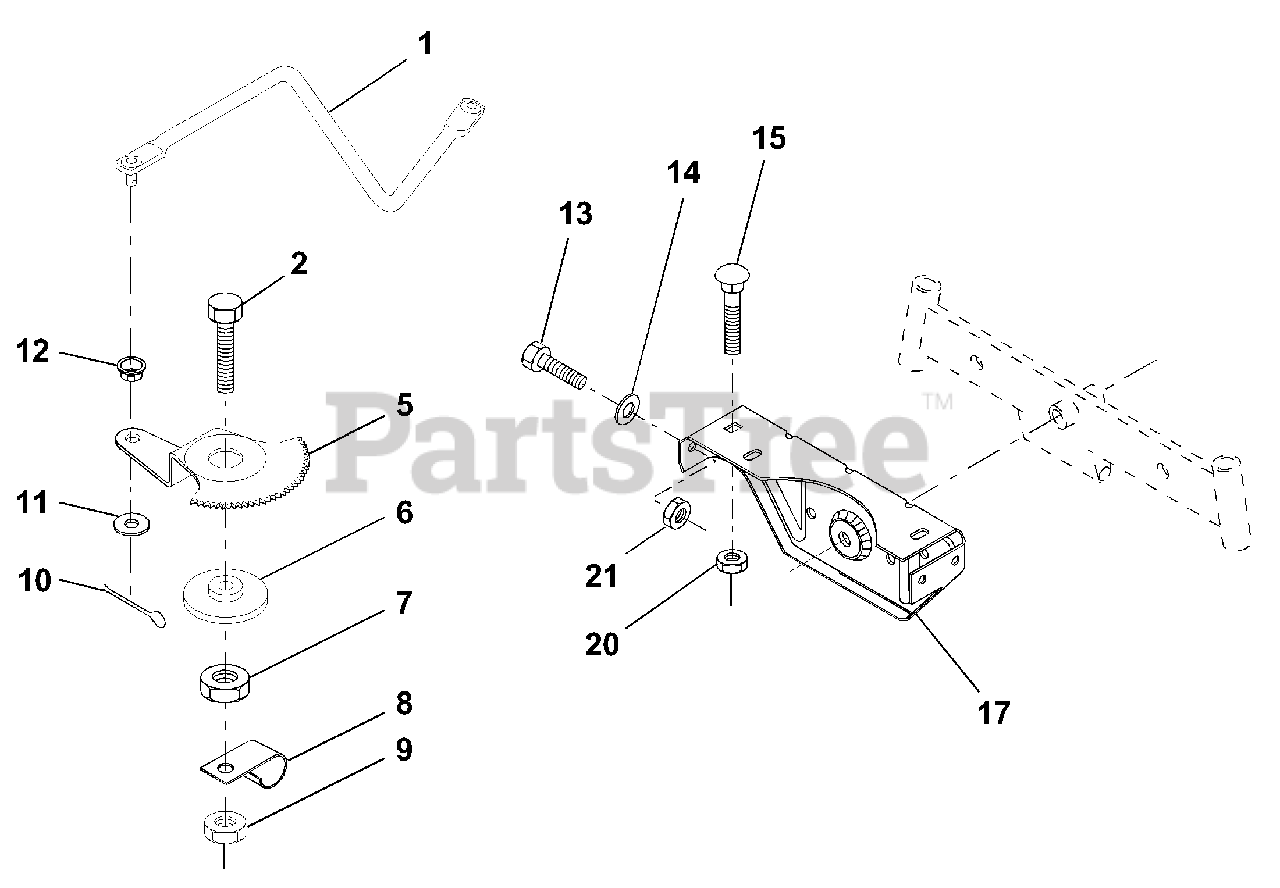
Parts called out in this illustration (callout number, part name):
1	Link, Drag
2	Bolt, Hex, Fin. 1/2-13 x 1-3/4
5	Gear, Sector
7	Nut, Heavy Hex, Top Lock 1/2-13 UNC
8	Clip, Insulated
9	Nut, Crownlock 3/8-16
10	Pin, Cotter 1/8 x 3/4
11	Washer 13/32 x 13/16 x 16 Gauge
13	Bolt, Hex Head 5/16-18 UNC x 1
14	Washer 11/32 x 7/8 x 16 Gauge
15	Bolt, Carriage 3/8-16 UNC x 3/4
17	Support, Front Axle
20	Nut, Hex, Lock Hex w/wsh 3/8-16
21	Nut, Hex, Lock Hx w/Ins 5/16-18
